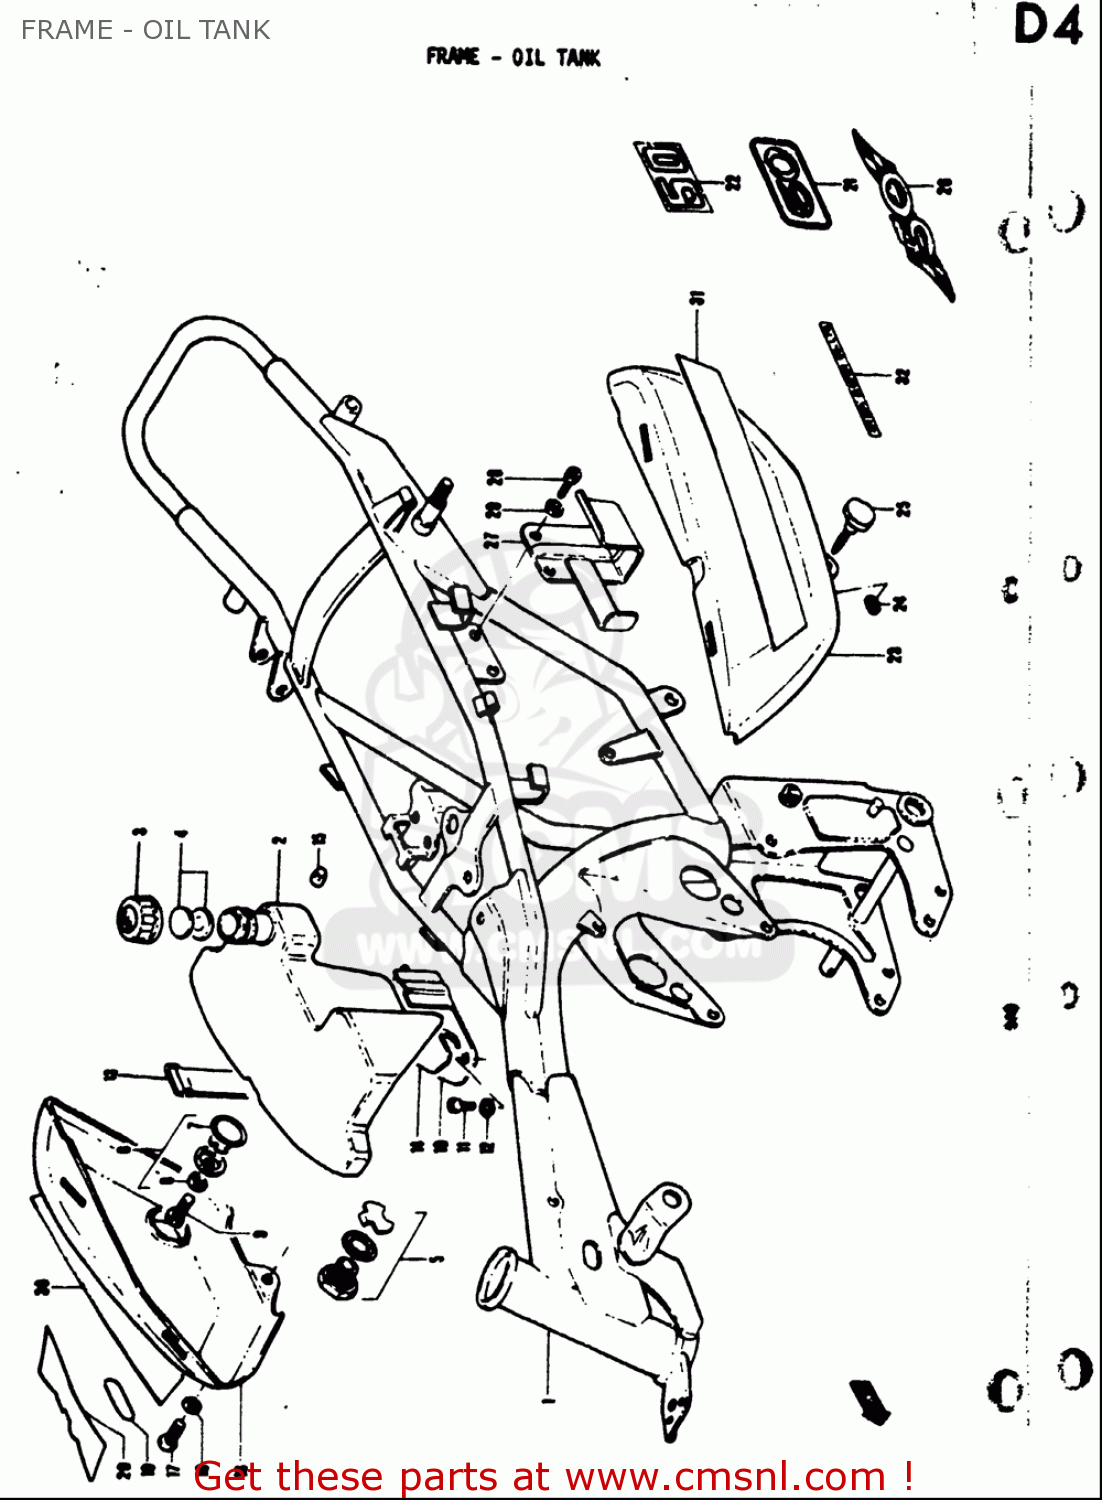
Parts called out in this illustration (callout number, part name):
3	CAP,OIL TANK
4	GASKET SET (NAS)
5	LENS SET,OIL LEVEL
7	O RING(D:3,ID:23)
8	GASKET(5X9.5X1) (NAS)
9	SCREW
12	WASHER,LOCK
13	BAND
15	CUSHION
17	SCREW
18	WASHER(6.5X16X1.2)
19	EMBLEM,CCIS
28	SCREW(6X10)
29	WASHER,LOCK
